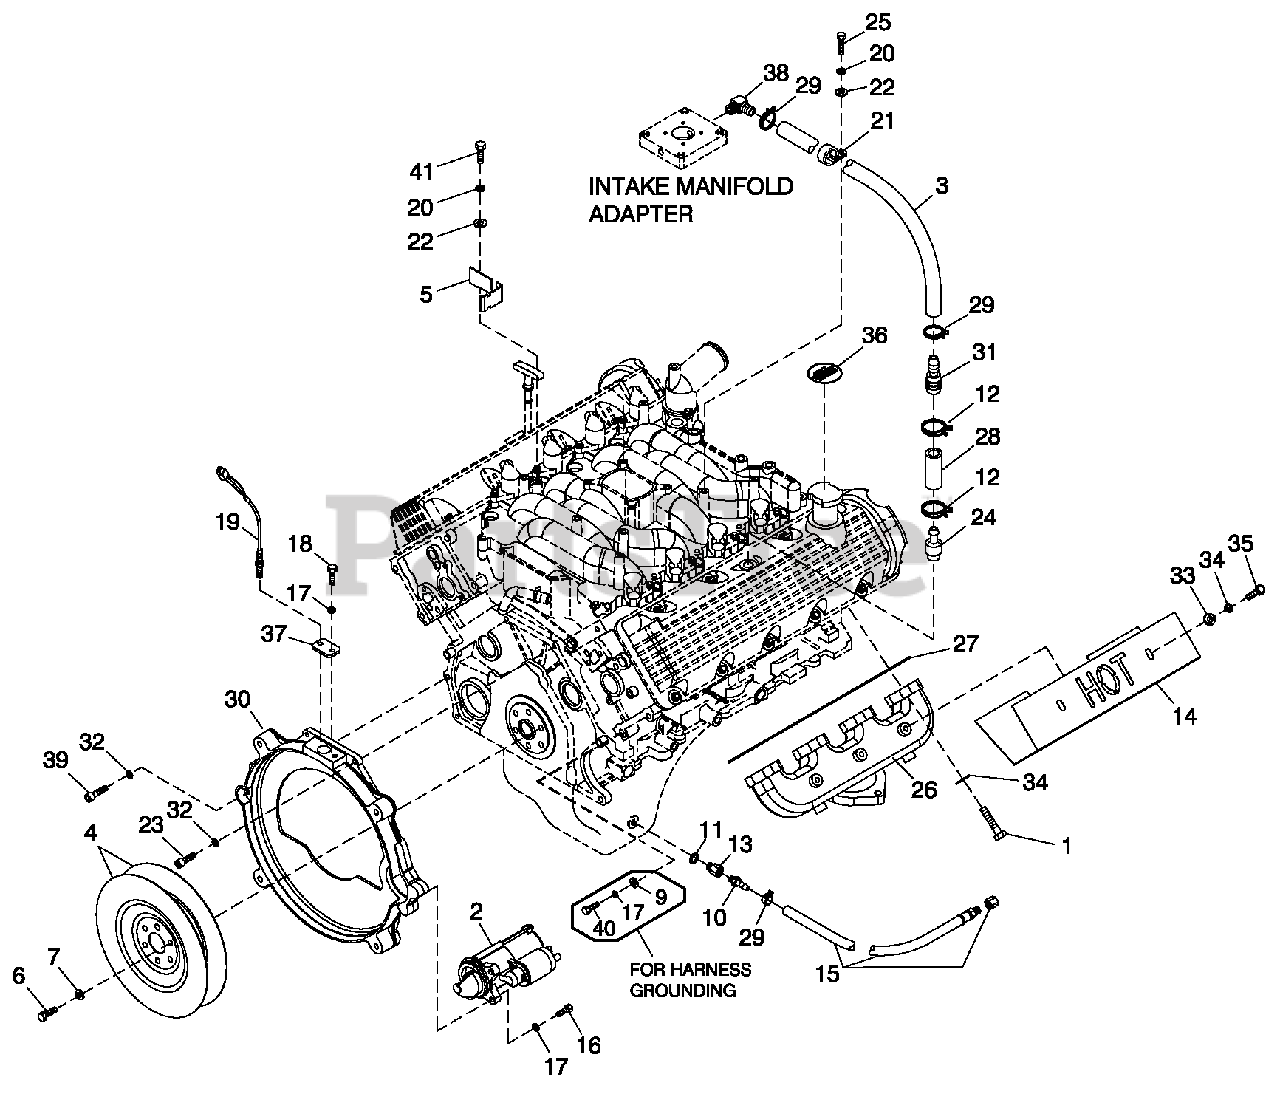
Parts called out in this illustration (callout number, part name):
1	SCREW SHC M8-1.25 X 35 SS
2	STARTER MOTOR 12V
3	HOSE 3/8 ID SINGLE BRAID (12"LG)
4	FLEX PLATE 2 POLE 4.6L G3
5	BRACKET, SIGNAL CONDITIONER
6	SCREW HHC M10-1.0 X 25 G10.9
7	WASHER FLAT .43 X 1.00
9	WASHER FLAT 5/16-M8 ZINC
10	BARBED STR 3/8 NPT X 3/8
11	WASHER NYLON .565
12	CLAMP HOSE BAND .88"
13	ADAPTER M14-1.50 X 3/8 NPT
14	HEAT SHLD EXHAUST MANIFOLD
15	HOSE DRAIN ASSY 28"
16	SCREW HHC M8-1.25 X 30 G8.8
17	WASHER LOCK M8-5/16
18	SCREW HHC M8-1.25 X 20 G8.8
19	ASSY MAGPICKUP(3/8-24 MALE)
20	WASHER LOCK M6-1/4
21	CLAMP VINYL .75 X .343 Z
22	WASHER FLAT 1/4 ZINC
23	SCREW SHC M10-1.5 X 30 G12.9
24	VALVE PCV 4.6L G3
25	SCREW HHC M6-1.0 X 16 G8.8
26	MACHINED MANIFOLD,EXHAUST
27	GASKET, EXHAUST MANIFOLD
28	HOSE COOL 5/8"ID 250#WP (2"LG)
29	HOSE CLAMP BAND 5/8"
30	ENGINE ADAPTER
31	HOSE BARB REDUCER 5/8"-3/8"ID
32	WASHER LOCK M10
33	WASHER FLAT M8 SS
34	WASHER LOCK M8 SSTL
35	SCREW HHC 5/16-18 X 1/2 SSTL
36	DECAL REFER TO OWNERS MANUAL
37	PLATE MAG PICK-UP ADAPTOR
38	BARBED EL 90 1/4NPT X 3/8
39	SCREW SHC M10-1.5 X 55 G12.9
40	SCREW HHC M8-1.25 X 25 G8.8
41	SCREW HHC M6-1.0 X 20 G8.8
